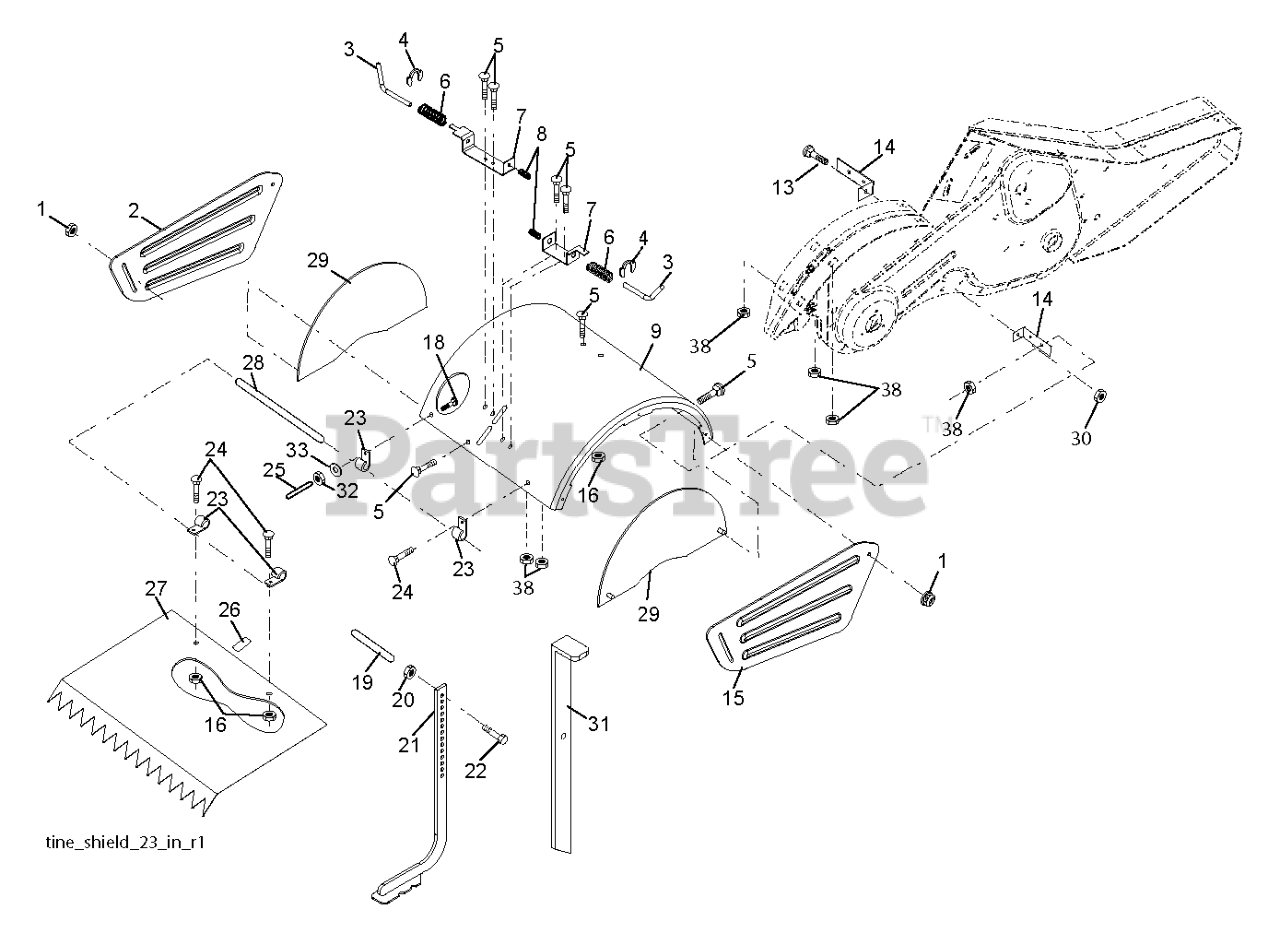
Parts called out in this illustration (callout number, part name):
1	NUT.FLANGE.5/16
2	SHIELD.PNT.SIDE.OUTER.LH.ORANG
3	STAKE PIN TI
4	RING, KLIP
5	BOLT, RDHD SQNK 5/16-18 X 3/4
7	BRACKET
8	SPRING CRT
9	SHIELD.TINE.DRT17.TILLER.ORANG
13	BOLT.CARRIAGE.5/16-18
14	BRACKET.TINE.SHIELD.BLACK
15	SHIELD.SIDE OUTER.RH.ORANGE
16	NUT T
20	NUT.HEX.3/8-16UNC
21	REPL BY 532 10 21-56
22	BOLT.375-16
25	VINYL CAP TI
26	PAD IDLER TI
27	SHIELD.LEVELING.17".ORANGE
28	PIN.HINGE.TILLER
29	SHIELD.TINE.SIDE.ORANGE.TILLER
30	LOCKNUT-FLANGE 5/16-18
31	STAKE.DEPTH.DRAG.BLACK.TILLER
32	NUT
33	LOCKWASHER
38	NUT
